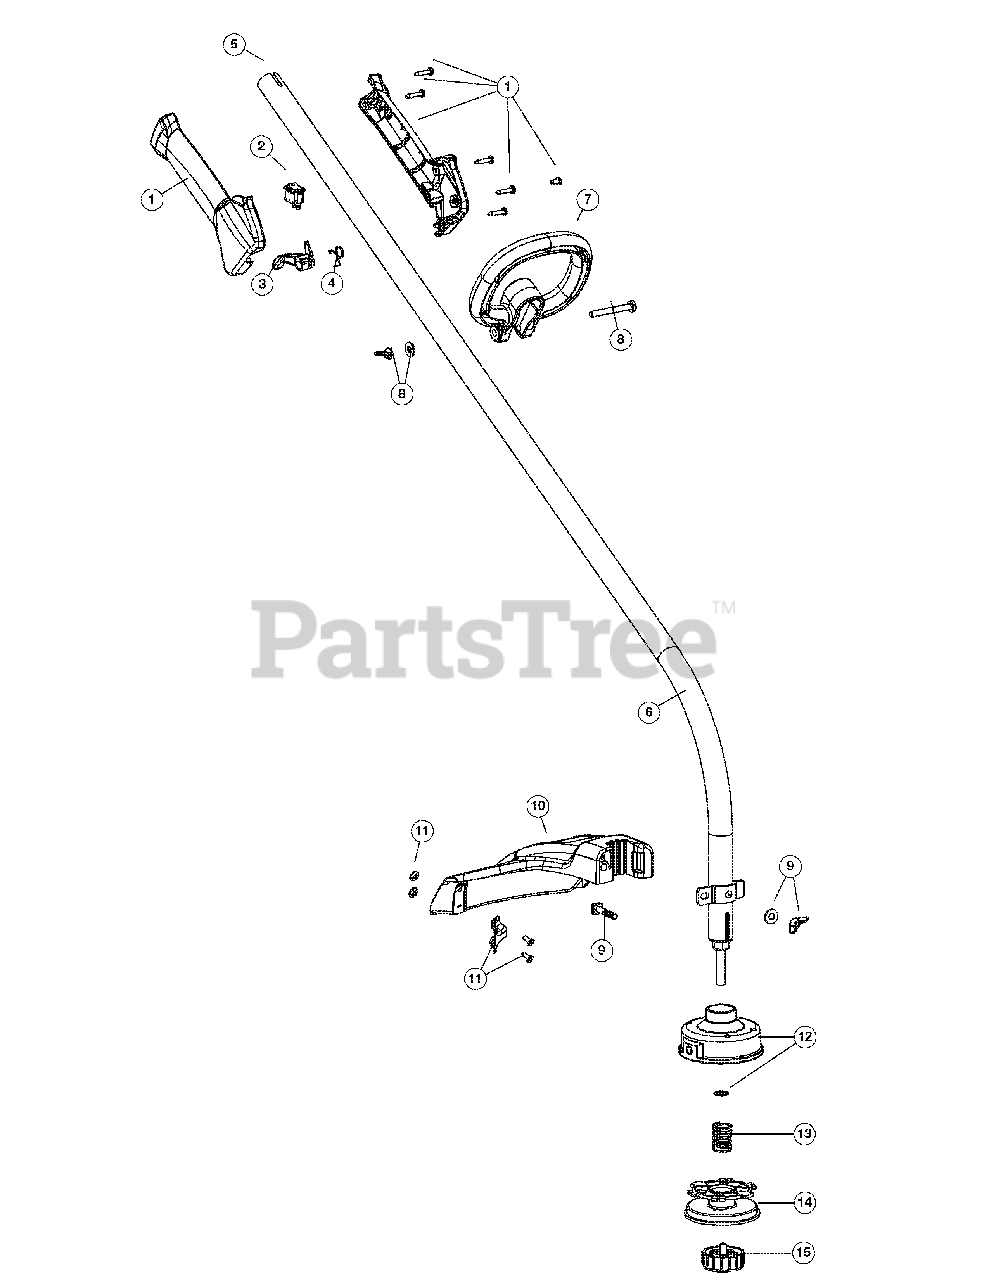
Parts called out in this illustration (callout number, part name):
1	Throttle Housing Assembly
3	Throttle Trigger
4	Throttle Trigger Spring
5	Flexible Drive Shaft
6	Drive Shaft Housing Assembly
7	D-Handle
8	D-Handle Hardware Assembly
9	Shield Mounting Hardware
10	Shield Assembly
11	Blade Assembly
12	Outer Spool w/Retainer
14	Inner Reel
15	Bump Head Knob Assembly
